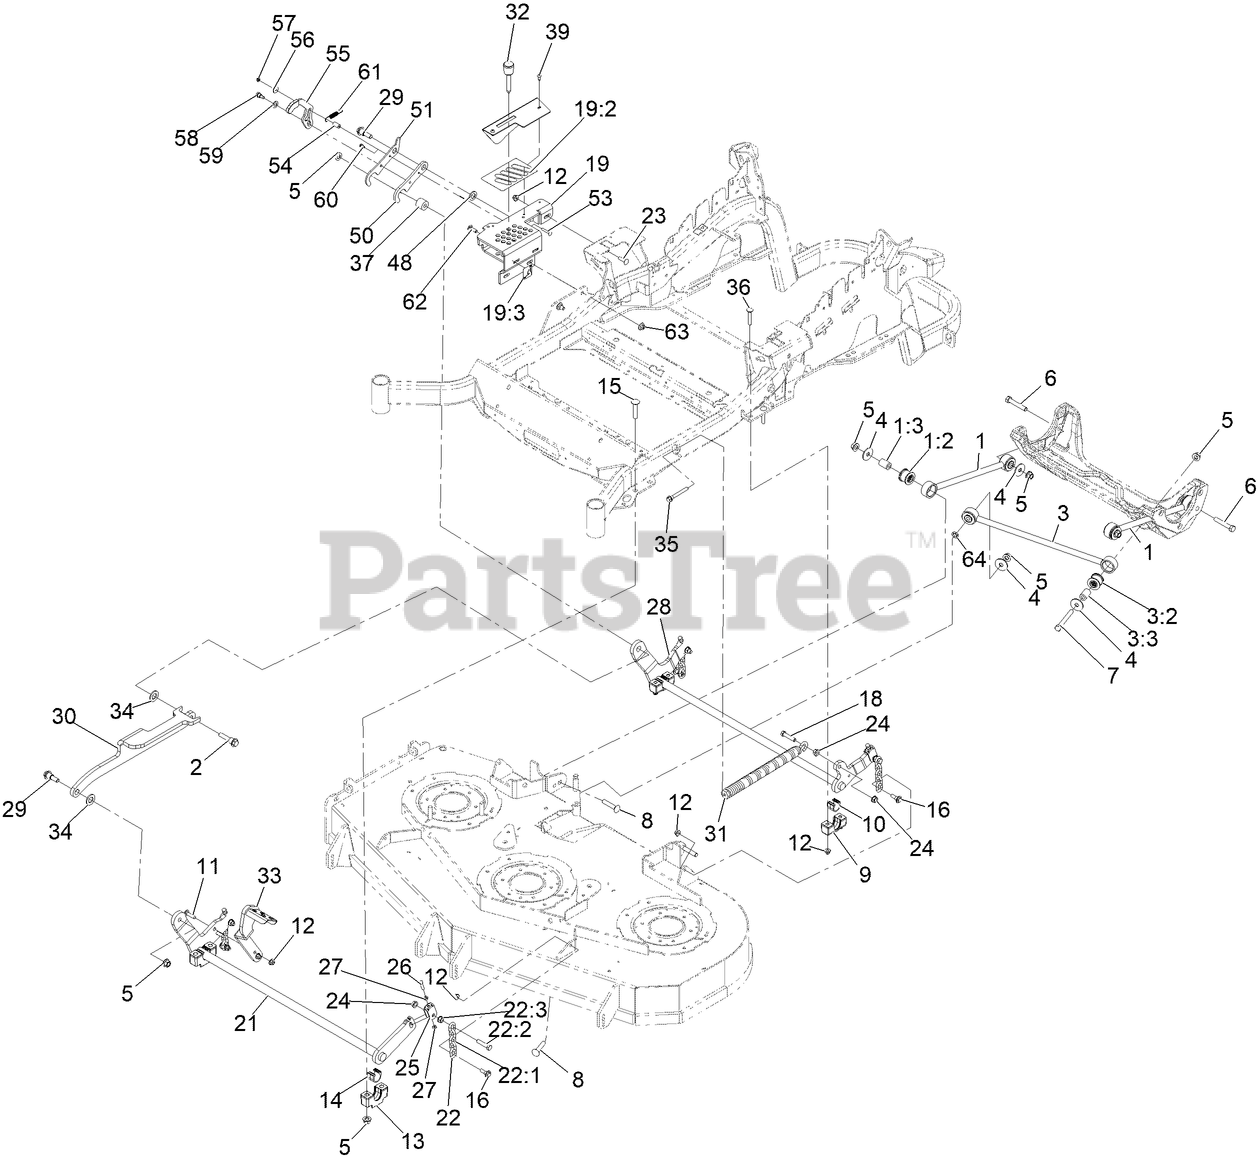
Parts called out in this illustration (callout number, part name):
1	DECK STRUT ASM
1:2	BUSHING-SUSPENSION, RUBBER
2	SCREW-HHF, SHOULDER
3	PANHARD ROD ASM
3:2	BUSHING-SUSPENSION, RUBBER
4	WASHER-THRUST
5	Nut-Lock 1/2-13
6	SCREW-HH
7	SCREW-HH
8	SCREW-CARR
9	SUPPORT-CROSS SHAFT, BEARING REAR
10	BEARING-CROSS SHAFT, REAR
11	SCREW-CARR
12	NUT-HF, NI
13	SUPPORT-CROSS SHAFT, BEARING
14	BEARING-CROSS SHAFT, FRON
15	Bolt-Carriage 1/2-13 X 2 1/2 Spl Neck
16	SCREW-SHOULDER, HHF
18	SCREW-HH
19	ASM-HOC Box W/ Decals
19:2	Decal-HOC
19:3	DECAL-PARK BRAKE, CE
21	Weld-Xshaft Front
22	DECK LIFT CHAIN ASM
22:1	CHAIN-LIFT, DECK
22:2	SCREW-HH
23	Bolt-Carriage 3/8-16 X 1 1/4
25	YOKE-ADJUST, DECK
26	SCREW-HH
27	NUT-JAM
28	Weld-Xshaft Rear
29	SCREW-SHOULDER, HHF 1/2-13 X 1.12
30	Link-Decklift
31	SPRING-EXTENSION
32	ASM- HOC PIN
33	LEVER-FOOT
34	WASHER-FLAT
35	BOLT-SHOULDER
36	Bolt-Carriage 3/8-16 X 2 1/4
37	Bushing- Link
39	SCREW-TPH THD FORM
50	Plate- Pawl
51	Plate- Pawl
53	SCREW-CARR
54	Spacer- 0.50" OD
55	Lever- Transport W/Grip
57	NUT-LOCK, NI
58	BOLT-SHOULDER
59	SPACER
60	SCREW-HWH
61	Spring- Extension
62	Bolt-Carriage 3/8-16 X 1 1/4
63	Nut-Nyloc 3/8-16 Flg
64	NUT-PUSH
